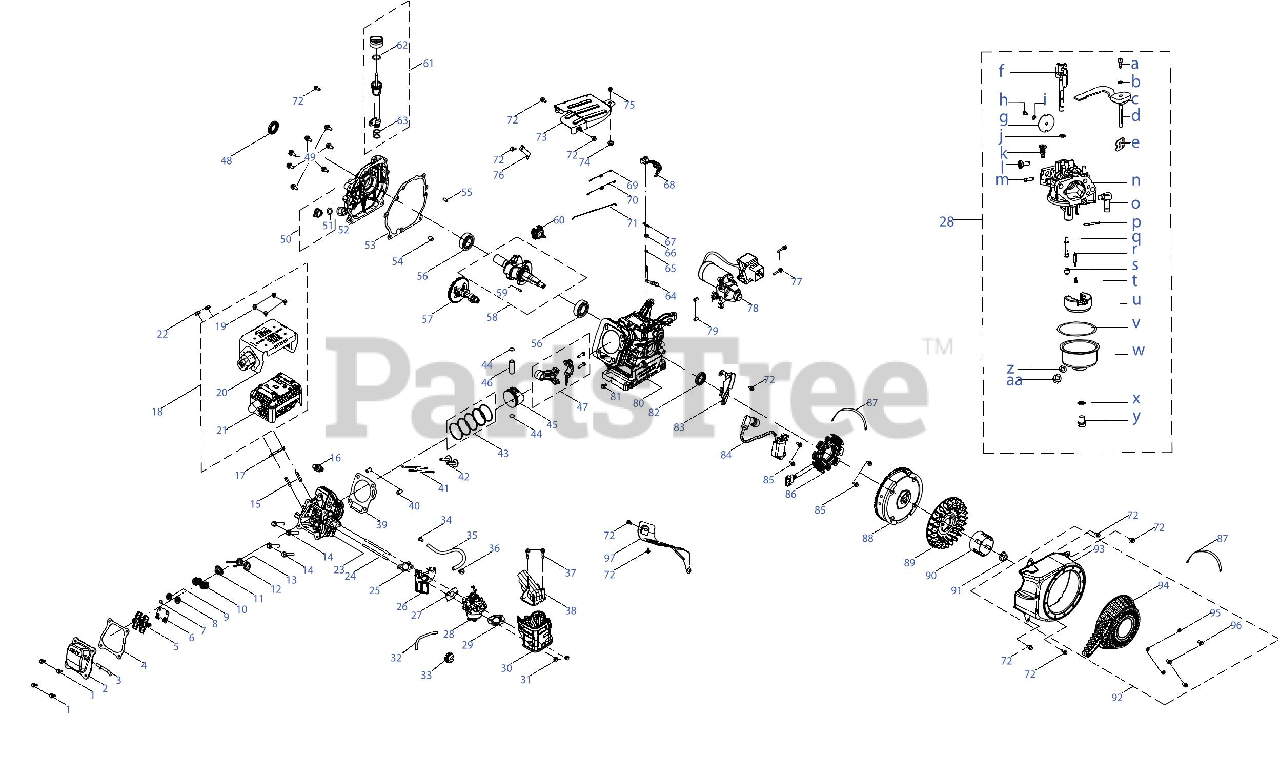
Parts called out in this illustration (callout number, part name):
1	Bolt, M6x16
2	Valve Cover
3	Breather Hose
4	Gasket, Valve Cover
5	Rocker Arm Assembly
6	Rocker Arm Base
7	Valve Adjust Cap, Exhaust
8	Valve Spring Seat
9	Valve Spring Seat
10	Valve Spring
11	Intake Valve Seal
12	Intake Vavle
13	Exhaust Valve
14	Bolt, M8x55
15	Stud, M8x34
16	Spark Plug
17	Gasket, Muffler
19	Bolt, M5x8
20	Muffler Guard
21	Muffler Body
23	Cylinder Head
24	Stud, M6x110
25	Gasket, Carburetor Insulator
26	Insulator
27	Gasket, Carburetor
28	Carburetor
29	Gasket, Carburetor
30	Air Filter Base
32	Fuel Hose, 3.2x6.5x530
35	Fuel Hose, 6.3x12.5x300
36	Clamp
37	Self-tappling Screw, ST4.2x45
38	Heater Box
39	Gasket, Cylinder Head
40	Pin, 10x16
41	Push Rod
43	Piston Ring Set
46	Piston Pin
47	Connecting Rod Assembly
48	Oil Seal, 25x41.25x6
49	Bolt, M8x32
51	O-Ring, 15.8x2.5
52	Crankcase Cover
53	Gasket, Crankcase
54	Pin, 9x14
55	Pin, 7x14
56	Bearing, 6205
58	Crankshaft
59	Woodruff Key
60	Governor Gear
61	Dipstick
62	O-Ring, 21x2.77
63	O-Ring, 15.5x1.5
64	Governor Gear Shaft
65	O-Ring, 5.2x1.9
66	Oil Seal, 6x11x4
67	Cotter Pin
68	Governor Lever
69	Governor Spring
70	Idle Spring
71	Throttle Linkage
72	Bolt, M6x12
73	Governor Shield
75	Bolt, M6x28
76	Spring Rack
77	Bolt, M6x32
78	Electric Starter
79	Pin, 8x8
81	Earth Bolt
82	Oil Seal, 25x41.25x6
83	Lower Shield
84	Ignition Module
85	Bolt, M6x25
86	Charging Coil
87	Tape, L=150mm
88	Flywheel
89	Cooling Fan
90	Starter Cup
91	Nut, M14x1.5
92	Recoil Starter
93	Blower Housing
94	Recoil Starter
95	Washer, 6
96	Bolt, M6x10
